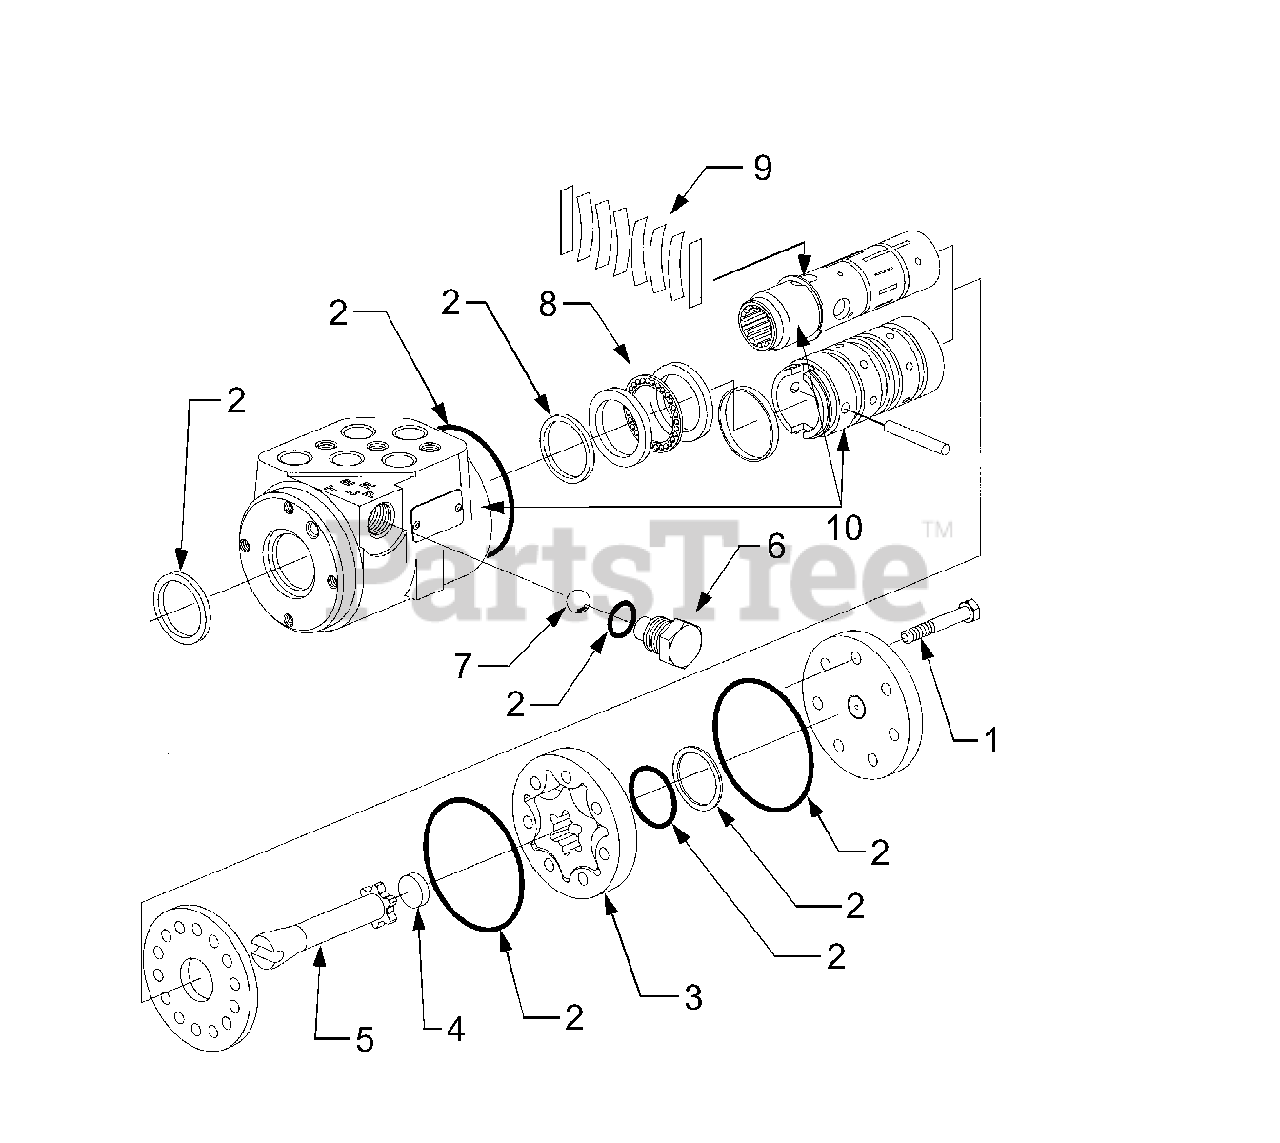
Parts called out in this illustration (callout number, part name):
1	Screw, Hex Cap, 1.57" Lg.
2	Seal Kit
3	Gerotor Assembly
4	Spacer, .240 Lg.
6	Plug, Manual Check
7	Ball, Manual Check
9	Spring Kit, Centering
10	Spool, Sleeve and Housing
